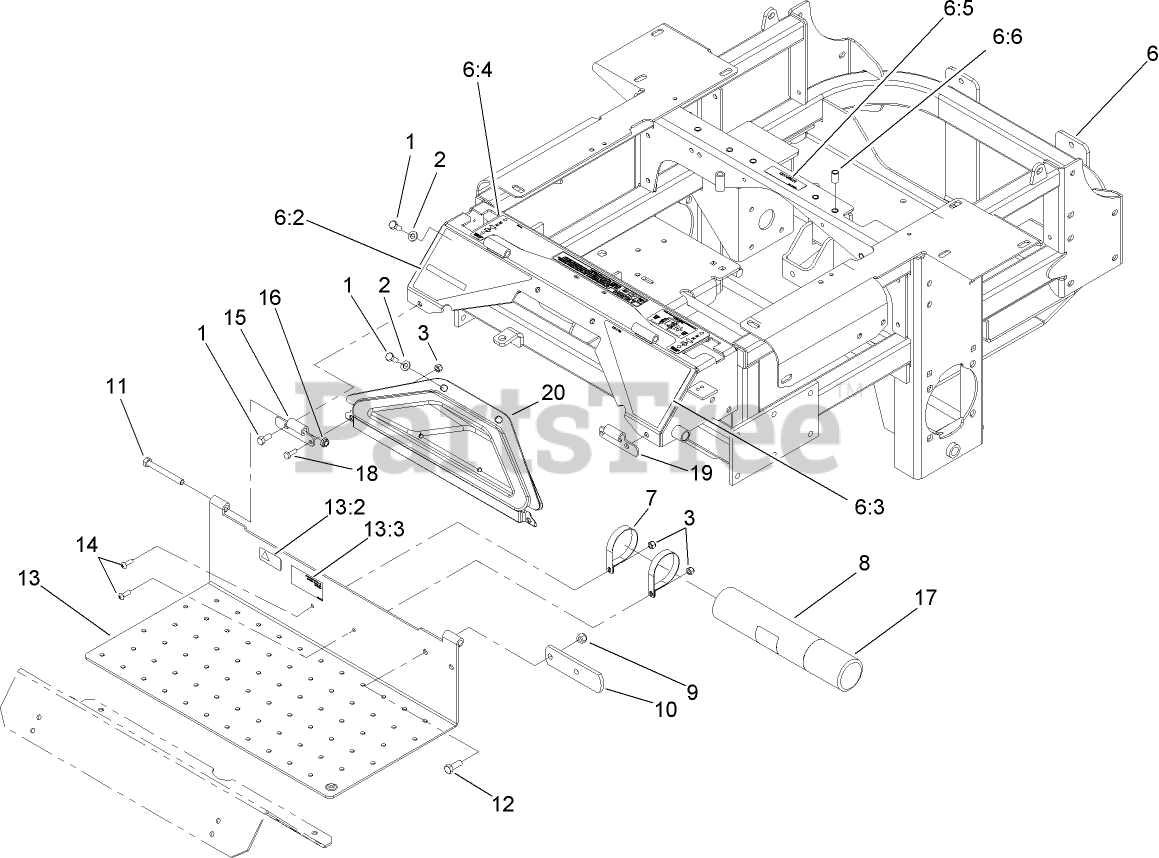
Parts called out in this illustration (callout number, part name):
1	SCREW-HH
2	WASHER-FLAT
3	NUT-LOCK, NI
6	MAIN FRAME ASM
6:2	Decal-Warning
6:3	Decal-Danger
6:4	DECAL-CONSOLE, TOP
6:5	DECAL-COVER, MISSING
6:6	INSERT-THREADED
7	R-Clamp
8	TUBE-MANUAL
9	NUT-LOCK, NI
10	STOP-BRAKE, PARK
11	SCREW-HH
12	SCREW-HH
13	FLOORPAN
13:2	DECAL-PROTECTION, EAR
13:3	Decal-Location, Manual
14	SCREW-PRH
15	Hinge-Floorpan, LH
16	NUT-LOCK, NI
17	CAP-HOUSING
18	SCREW-HH
19	Hinge-Floorpan, RH
20	Pocket
